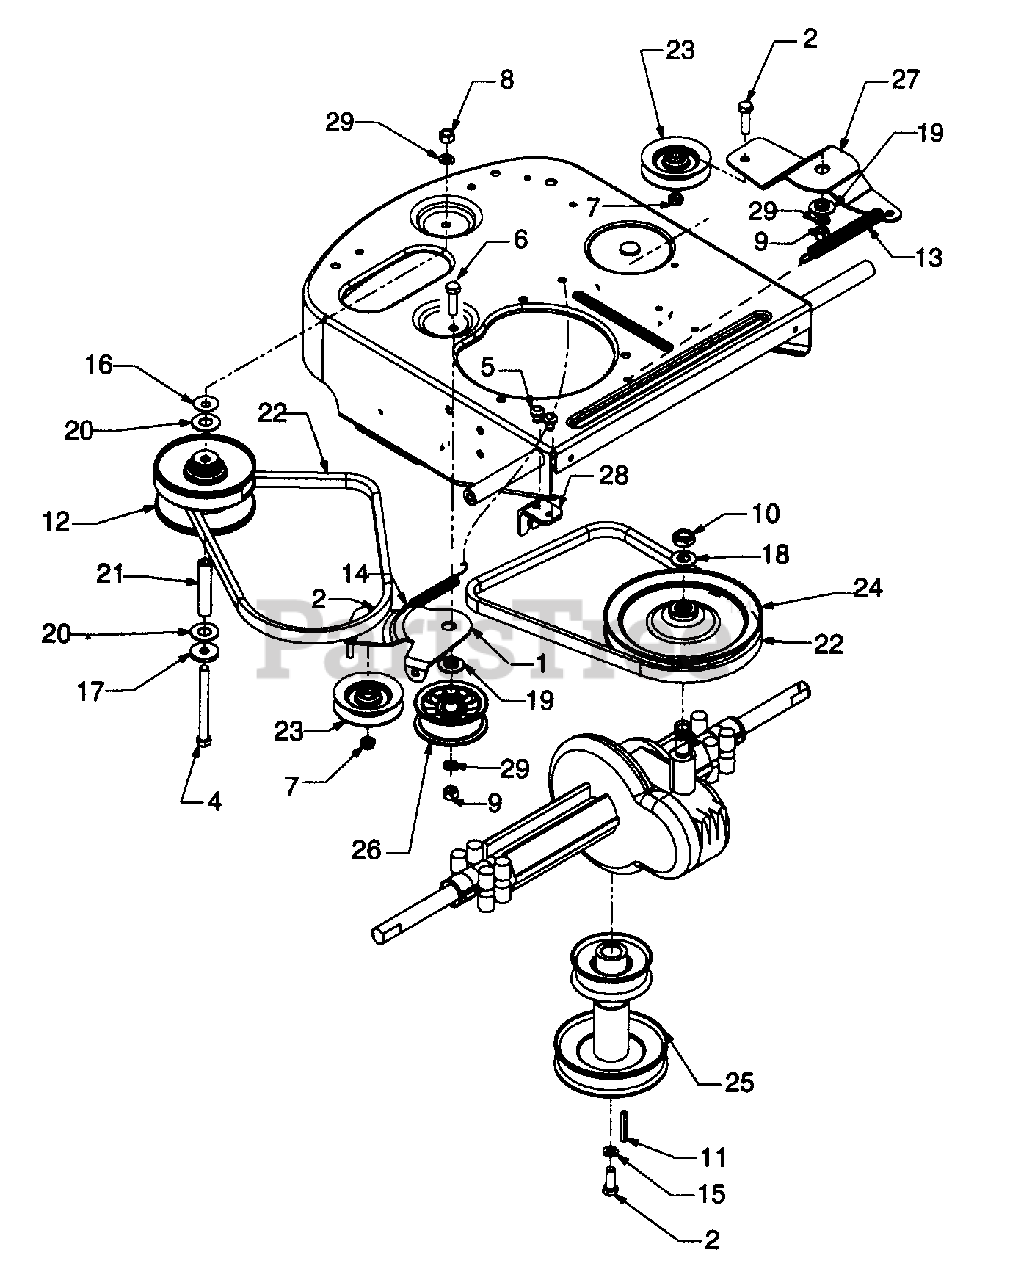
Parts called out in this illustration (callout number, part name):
1	Idler Bracket Assembly
2	Hex Screw 3/8-24 x 1.00
4	Cap Screw 3/8-24 x 3.75
5	Pan Head TL Screw 5/16-18 x .75
6	Hex Screw 3/8-16 x 2.0 Special
7	Jam Lock Nut 3/8-24
8	Hex Nut 3/8-24
9	Hex Nut 3/8-16
10	Hex Jam Nut 9/16-18 (Gr. 5)
11	Square Key
12	Variable Speed Pulley Assembly
13	Extension Spring
14	Extension Spring
15	Lock Washer 7/16 I.D.
16	Bell Washer .406 I.D. x 1.13 O.D.
17	Flat Washer 3/8 x 1.25 O.D.
18	Belleville Washer .567 x 1.125 x .06
19	Shoulder spacer
20	Bearing
21	Spacer
22	V-Belt
23	Idler Pulley
24	Transmission Pulley
25	Engine Pulley
26	Flat Idler Pulley
27	Idler Bracket
